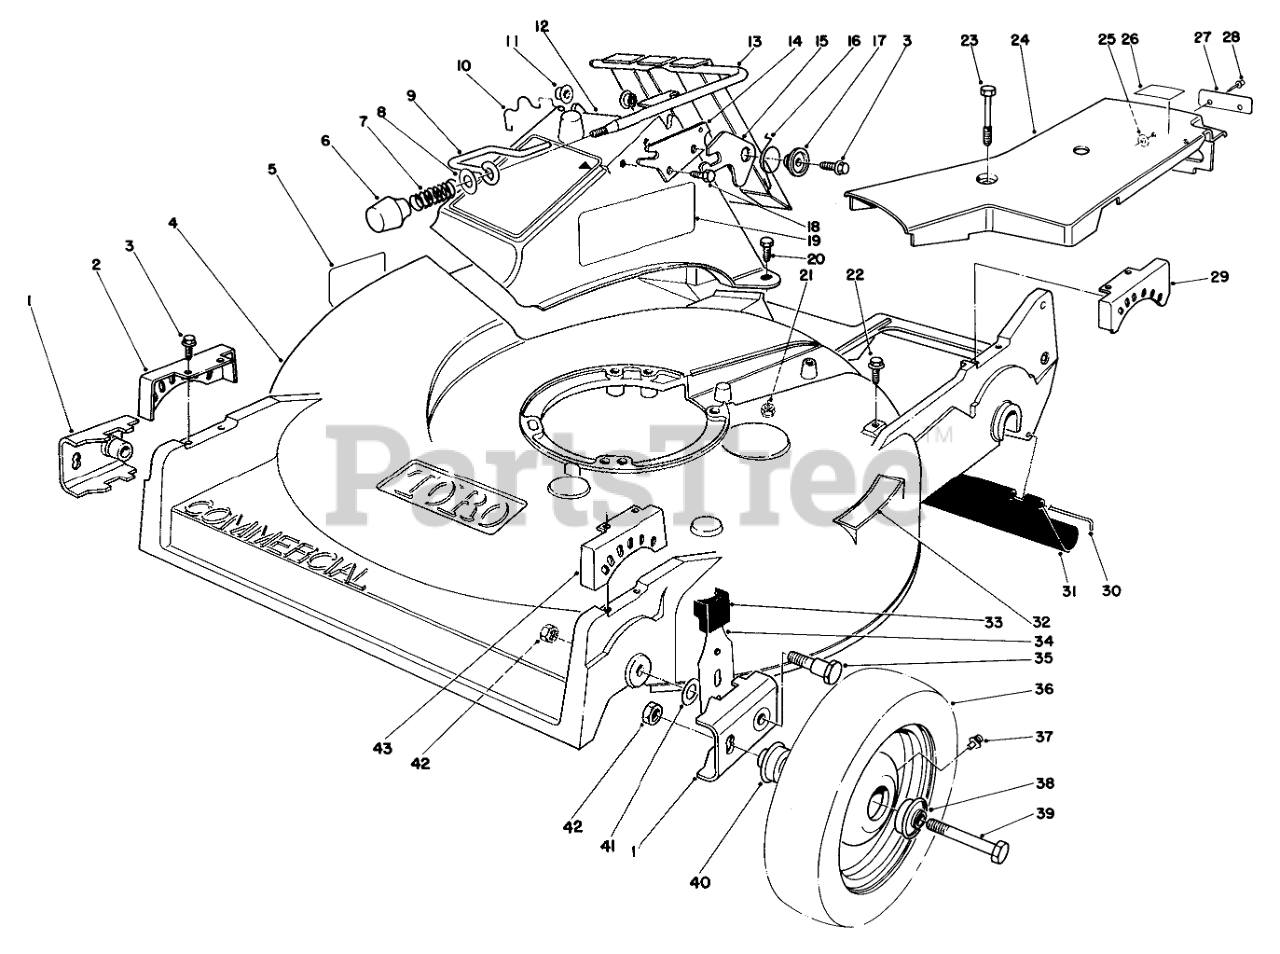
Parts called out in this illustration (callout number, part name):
1	PIVOT ARM
2	QUADRANT-FRONT, RH
3	Screw
4	Housing
5	DECAL-DANGER
7	COMPRESSION SPRING
8	WASHER-FLAT
9	DOOR LATCH
10	DOOR RETAINER
11	BUSHING-NYLON
12	Chute & Door Assembly (Incl. Ref. # 3 & 6-21)
13	DOOR & HANDLE WA
14	DOOR LATCH PLATE
15	SAFETY LATCH
16	TORSION SPRING
17	DOOR SPACER
18	SCREW-HWH
19	DECAL SAF INST
20	SCREW-HH
21	NUT-LOCK, NI
22	SCREW-HWHTF
23	SCREW-HHFTF
24	Belt Cover Assembly (Incl. Ref. #25 & 27-28)
25	WASHER-PLAIN
26	Label-Grease
27	NAMEPLATE-GRD SPEED
29	QUADRANT-REAR, LH
30	ROD-SHIELD
31	SHIELD-TRAILING
32	STEP PAD DECAL
33	KNOB-ARM
34	SPRING ARM ASM-FRONT
35	PIVOT SCREW
36	Wheel & Tire Assembly (Incl. Ref. #37-38 & 40)
37	FITTING-GREASE
38	WHEEL BRG
39	SCREW-HH
40	WHEEL BEARING
41	WASHER-PIVOT
42	NUT-LOCK, NI
43	QUADRANT-FRONT, LH
